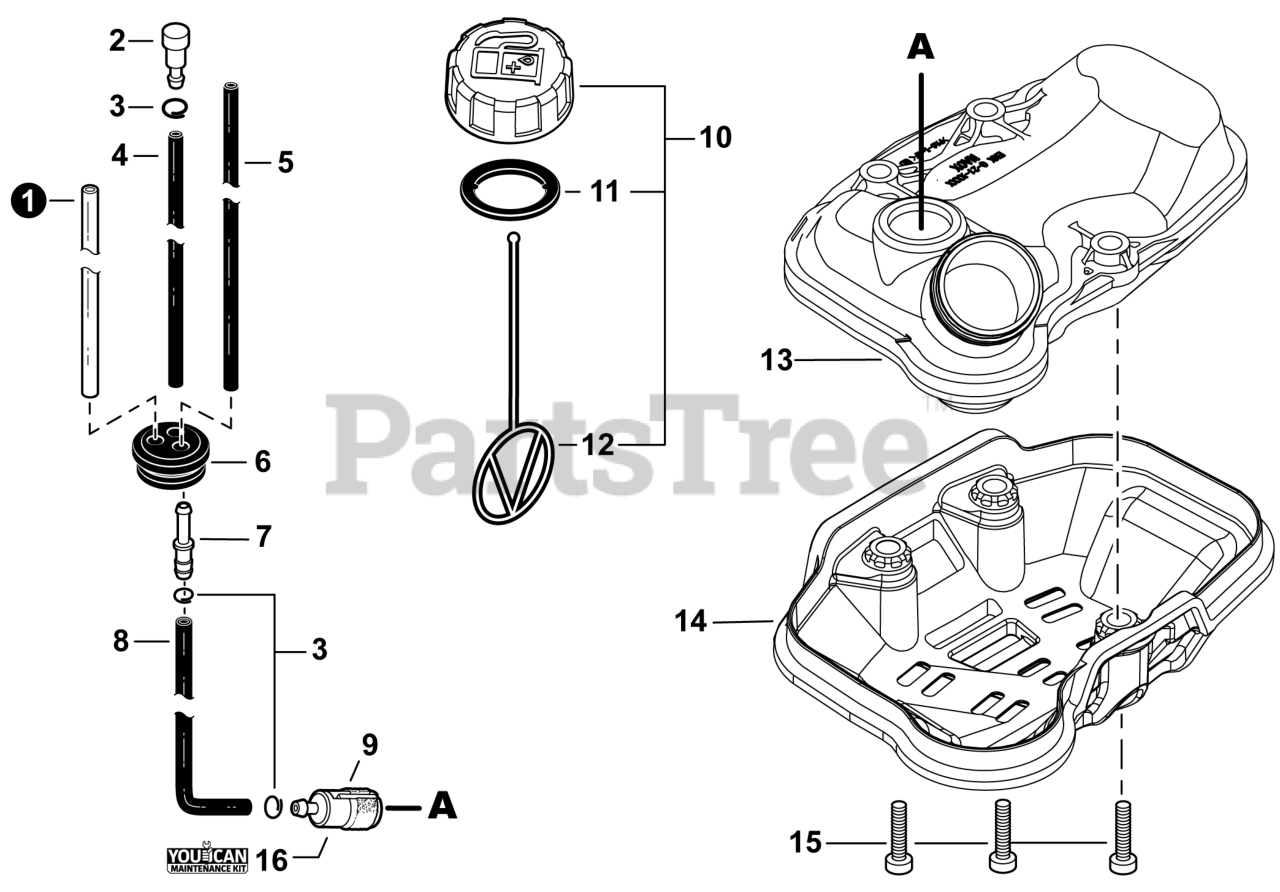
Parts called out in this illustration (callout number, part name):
1	PIPE, FUEL 3x6x85 YELLOW
2	VENT ASSY
4	PIPE, FUEL 3x5x90 BLACK
5	PIPE, FUEL 3x5.5x78 BLACK
6	GROMMET, FUEL
7	CONNECTOR, PIPE 5x3.5
8	PIPE, FUEL 3x5x90L BLACK
9	FILTER, FUEL
10	CAP ASSY, FUEL
11	GASKET, FUEL CAP
12	CONNECTOR, CAP L= 123
13	TANK ASSY, FUEL
14	GUARD, FUEL TANK
15	BOLT, TORX 5x25
16	TUNE-UP KIT - YOUCANT
